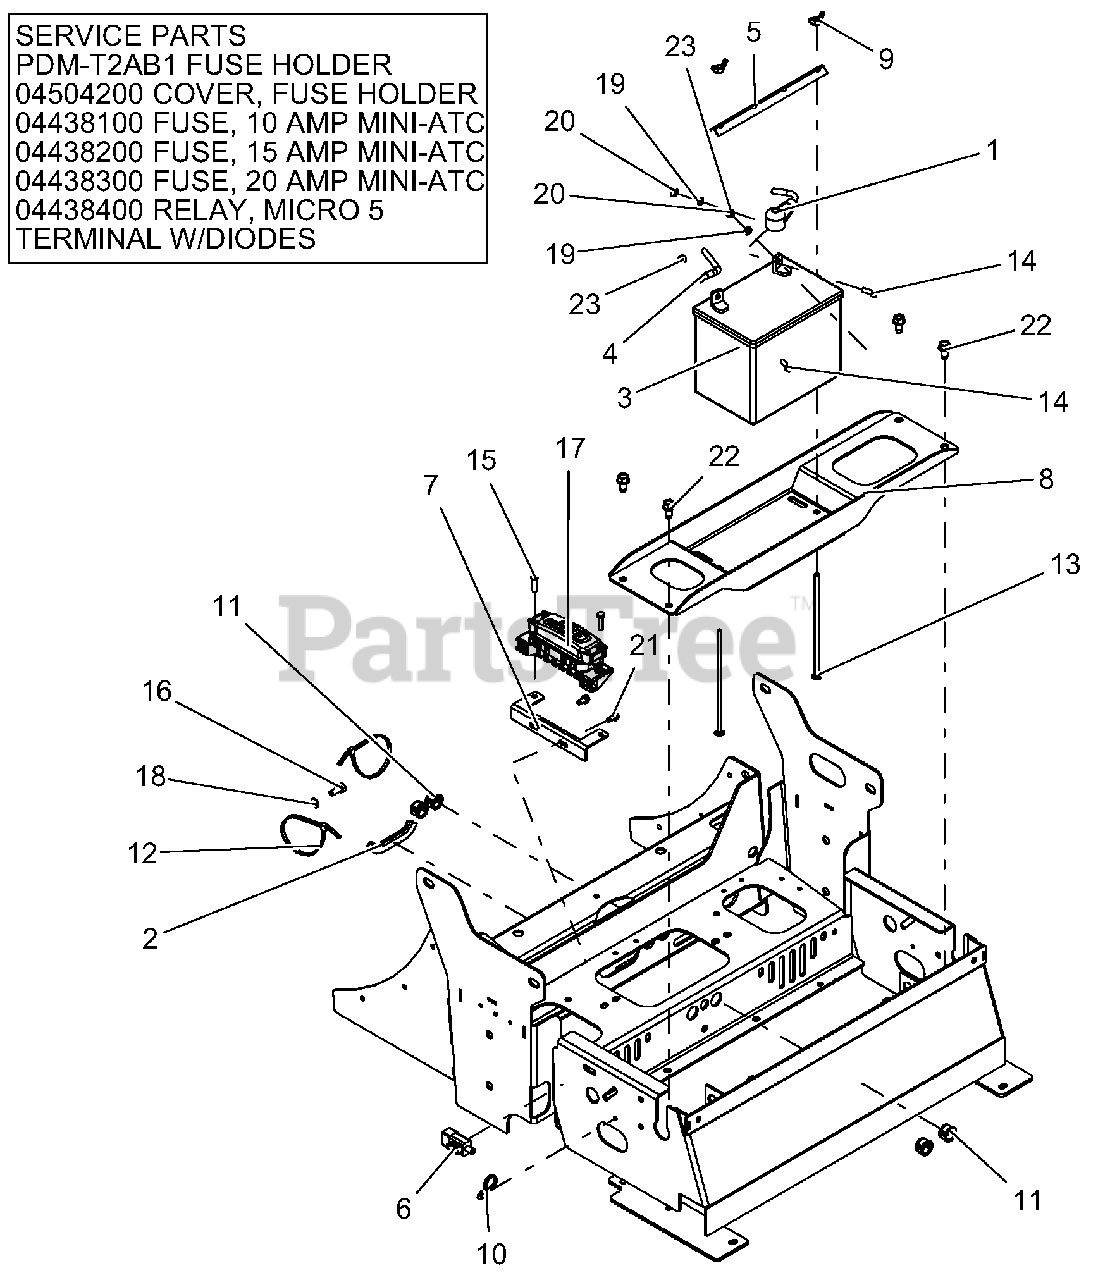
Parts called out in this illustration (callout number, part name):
1	CABLE, POS BATT W/ BOOTS 6 X 35
2	STRIP, COWL - 1.50 LG
3	BATTER,Y
4	CABLE, NEGATIVE BATTERY 35.00"
5	HOLD DOWN - BLK
6	SWITCH, SNAP IN -N.OO./N.
7	BRKT, FUSE HOLDER MOUNTING-RED
8	TRAY, BATTERY-RED
9	NUT-LOCKING WING 1/4-20
10	CABLE TIE W/ TREE (.25 HOLE)
11	BUSH, PANEL SNAP .687X.875X.56
12	CABLE, TIE 5.50 LG
13	BLT-RDHDSQNK .25-20X7.50 G2 YWZC
14	BLT-HEX .25-20X.75 GR5 YWZC
15	@BLT-HEX M6-1.0X25 YWZC
16	@BLT-HEX M8-1.25X20 YWZC
17	HARNESS, PT400 GAS WIRE
18	WSHR-LK .31X.078 REG YWZC
19	WSHR-LK .25X.062 REG YWZC
20	NUT-HEX .25-20 YWZC
21	SCR-TAP .25-20X.50 HWH TR YWZ
22	SCR-TAP .38-16X.75 HWH TR YWZ
23	WSHR-FL-STL.281X.62X.065 YWZC
